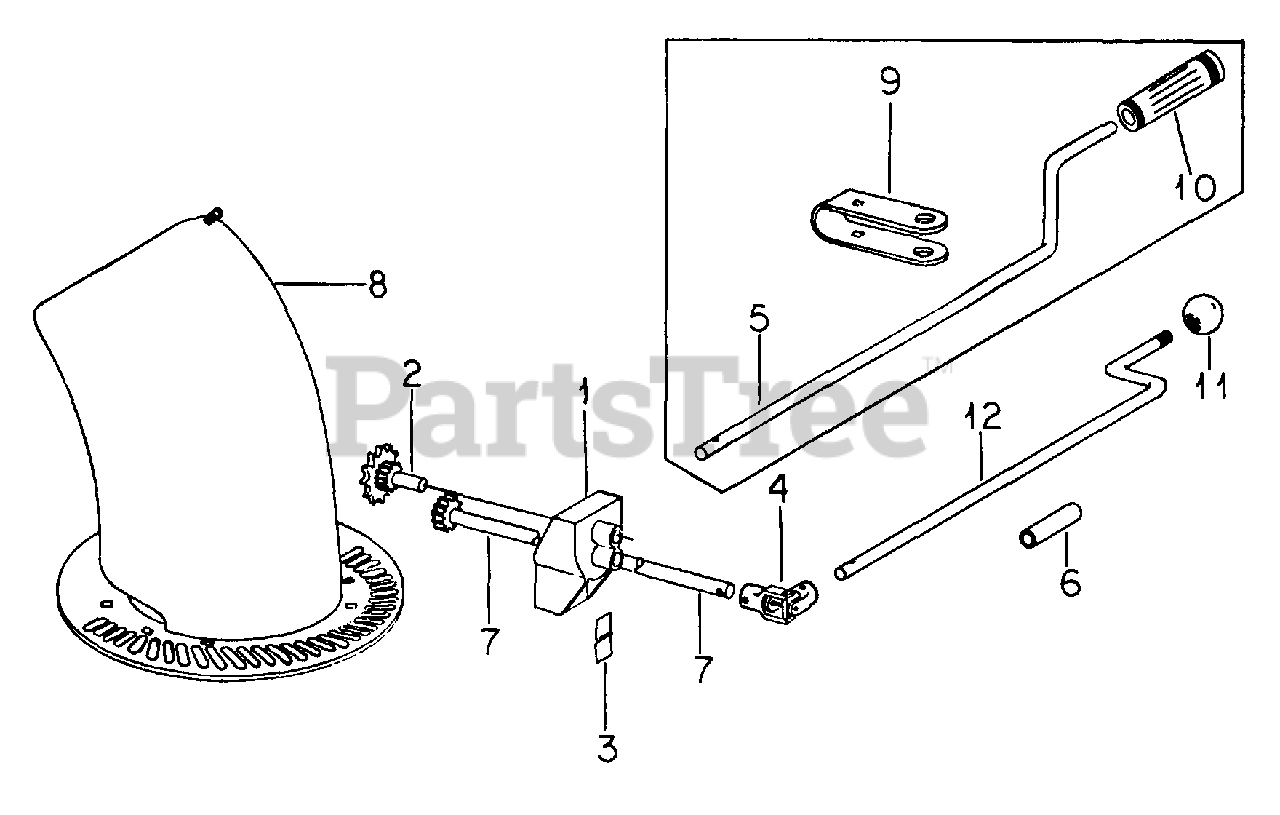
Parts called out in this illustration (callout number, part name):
1	SUPPORT, BEARING
2	SPROCKET ASSY
4	UNIVERSAL JOINT
5	HANDLE, CHUTE CONTROL
6	SLEEVE, CONTROL HANDLE
7	GEAR ASSY, DRIVE
8	CHUTE, SNOW
9	BRACKET, CHUTE CONTROL
10	GRIP, CHUTE CONTROL HANDLE
11	KNOB, CHUTE CONTROL ROD
12	ROD, CHUTE CONTROL
